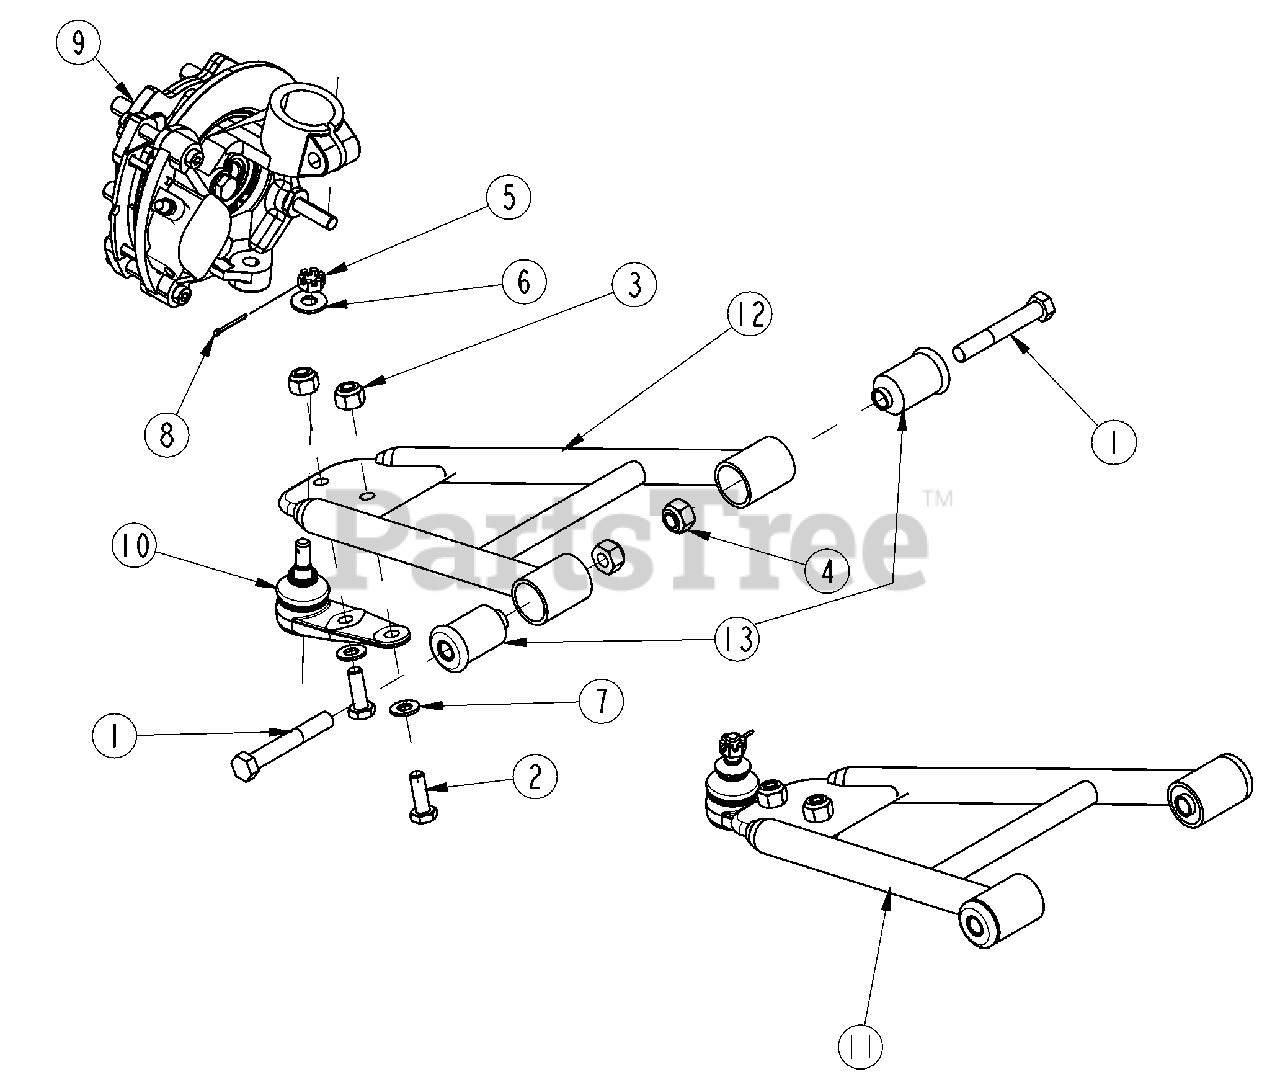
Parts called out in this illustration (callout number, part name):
1	HHCS M12 X 1.75 X 80 GR8.8 PLT
2	BOLT, M10 X 1.50 X 30 HEX 8.8
3	NUT, LOCK NYLON M10 X 1.5 PLT
4	NUT, LOCK NYLON M12 X 1.75 PLT
5	NUT, HEX, SLOTTED M10-1.25
6	WASHER, FLAT STEEL .438 X 1.00 X .083
7	WASHER, FLAT STEEL M10 10.5 X 20 X 2
8	PIN COTTER .09 X 1 LONG
9	RIGHT HAND DISC BRAKE ASM 172mm WITH JNT
10	BALL JOINT BOLT ON SIR
11	CONTROL ARM ASSEMBLY, LEFT HAND (Includes No. 2, 3, 5, 6, 7, 8, 10, 11, 12 & 13)
12	CONTROL ARM WELDMENT, LEFT HAND
13	BUSHING, A-ARM
